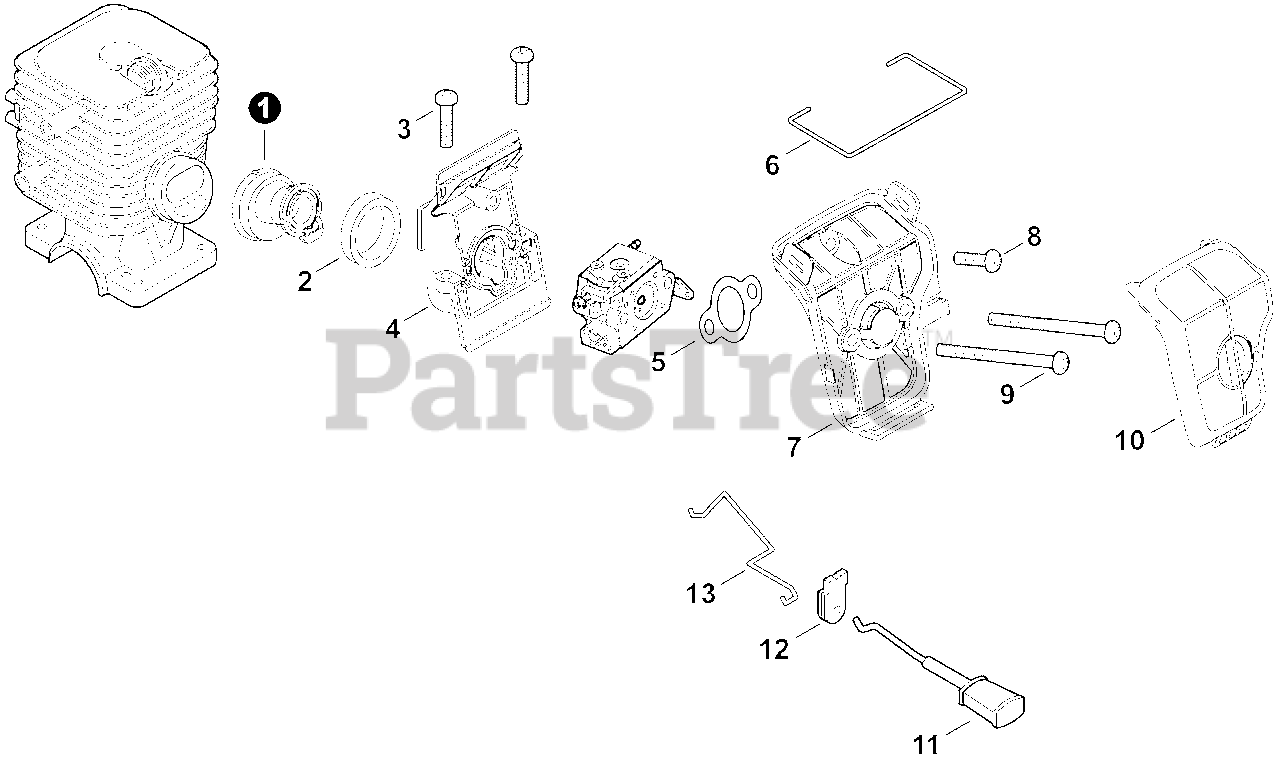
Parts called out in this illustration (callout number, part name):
1	BELLOWS, INTAKE
2	RETAINER, BELLOWS
3	BOLT, TORX 5×20
4	INSULATOR, INTAKE
5	GASKET, INTAKE
6	RETAINER, AIR FILTER
7	CASE, AIR FILTER
8	BOLT, TORX 5×16
9	BOLT, TORX 5×55
10	FILTER, AIR
11	ROD, CHOKE
12	GROMMET, CHOKE
13	ROD, THROTTLE
